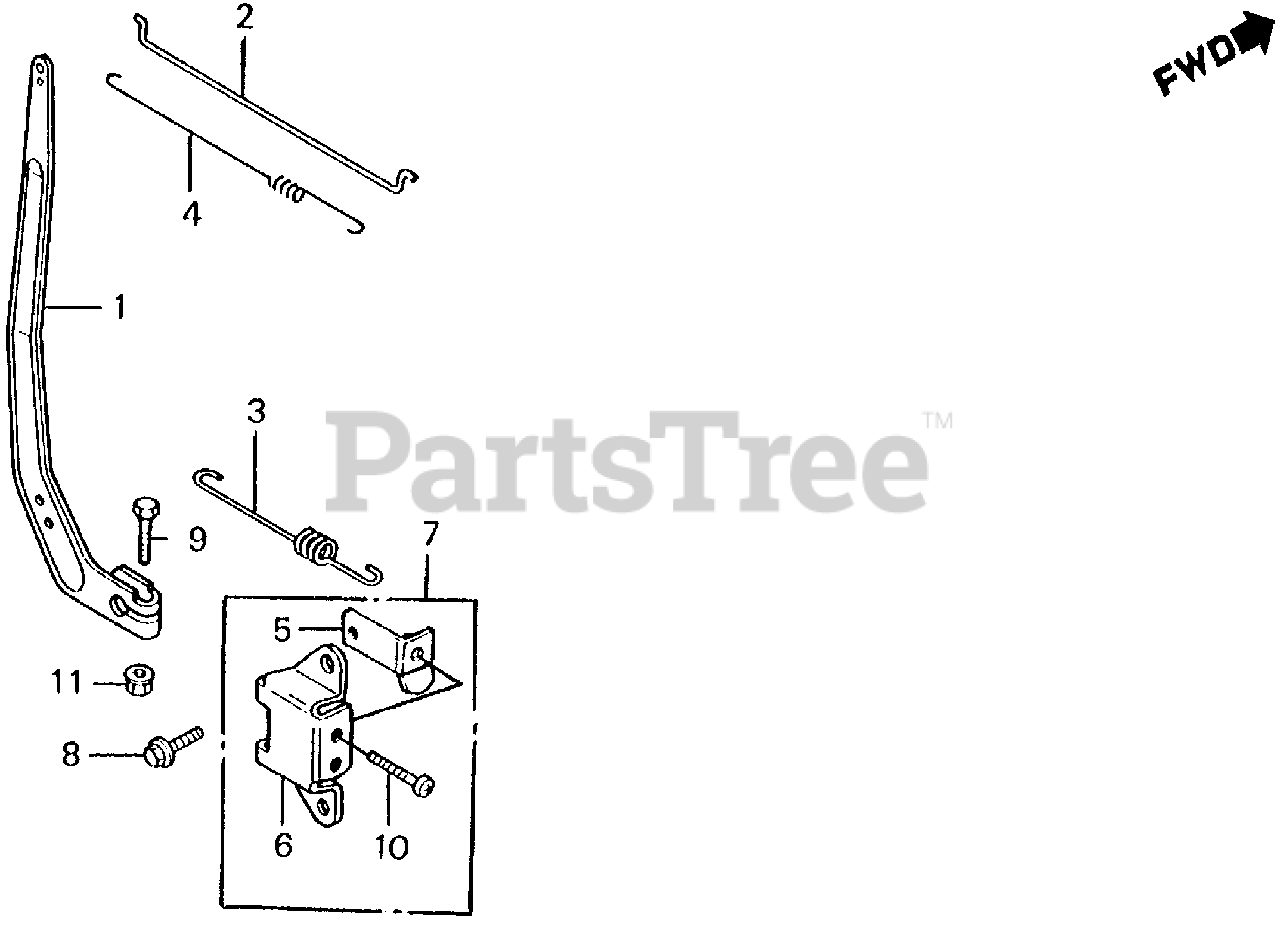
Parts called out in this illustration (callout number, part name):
1	ARM, GOVERNOR
2	ROD, GOVERNOR
3	SPRING, GOVERNOR
4	SPRING, THROTTLE RETURN
5	PLATE, CONTROL
6	BASE, CONTROL
7	LEVER, CONTROL
8	BOLT, FLANGE (6X12) (CT200)
9	BOLT, HEX. (6X20)
10	SCREW, PAN (6X28)
11	NUT, FLANGE (6MM)
